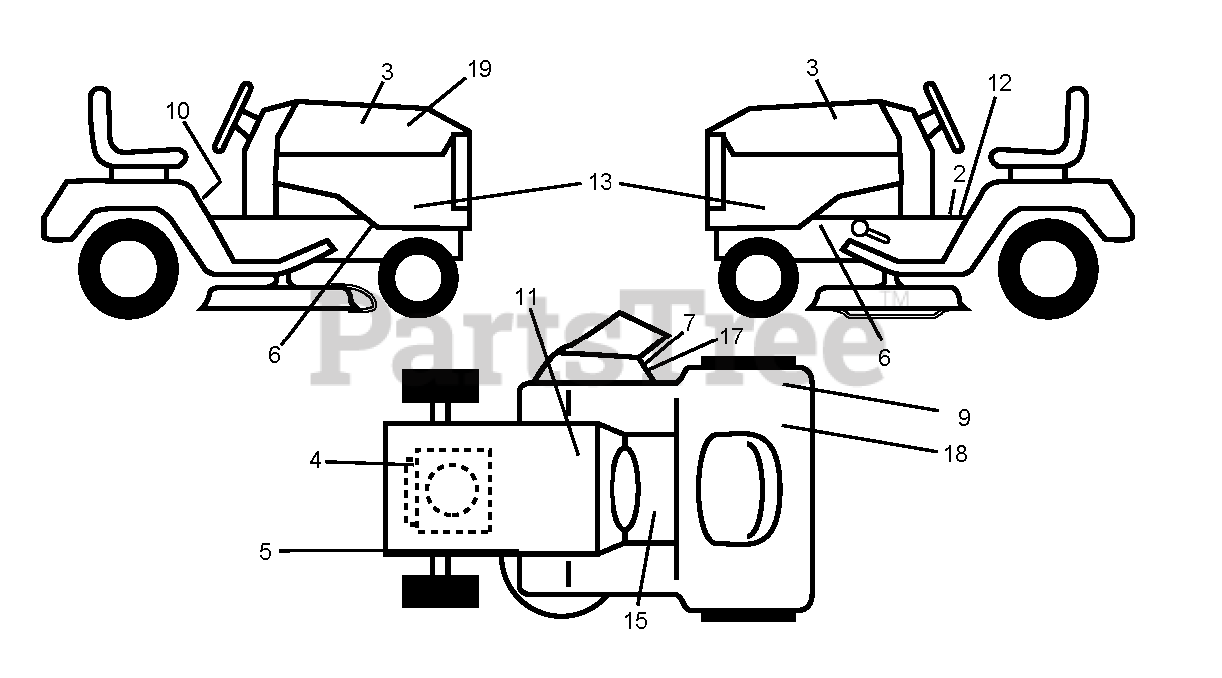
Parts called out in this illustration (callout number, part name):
2	DECAL PARK BRAKE
3	RP.DECAL.BADGE.170MM.TEXTLOGO
4	DECAL
5	DECAL V BELT SCHEMATIC
7	DECAL.INTERNATIONL.CUTFINGER
9	DECAL
10	LABEL
11	DECAL BTRY SYMBOLS
12	DECAL
15	DECAL
17	DECAL, DEFLECT WARNING
18	DECAL 80 DBA
